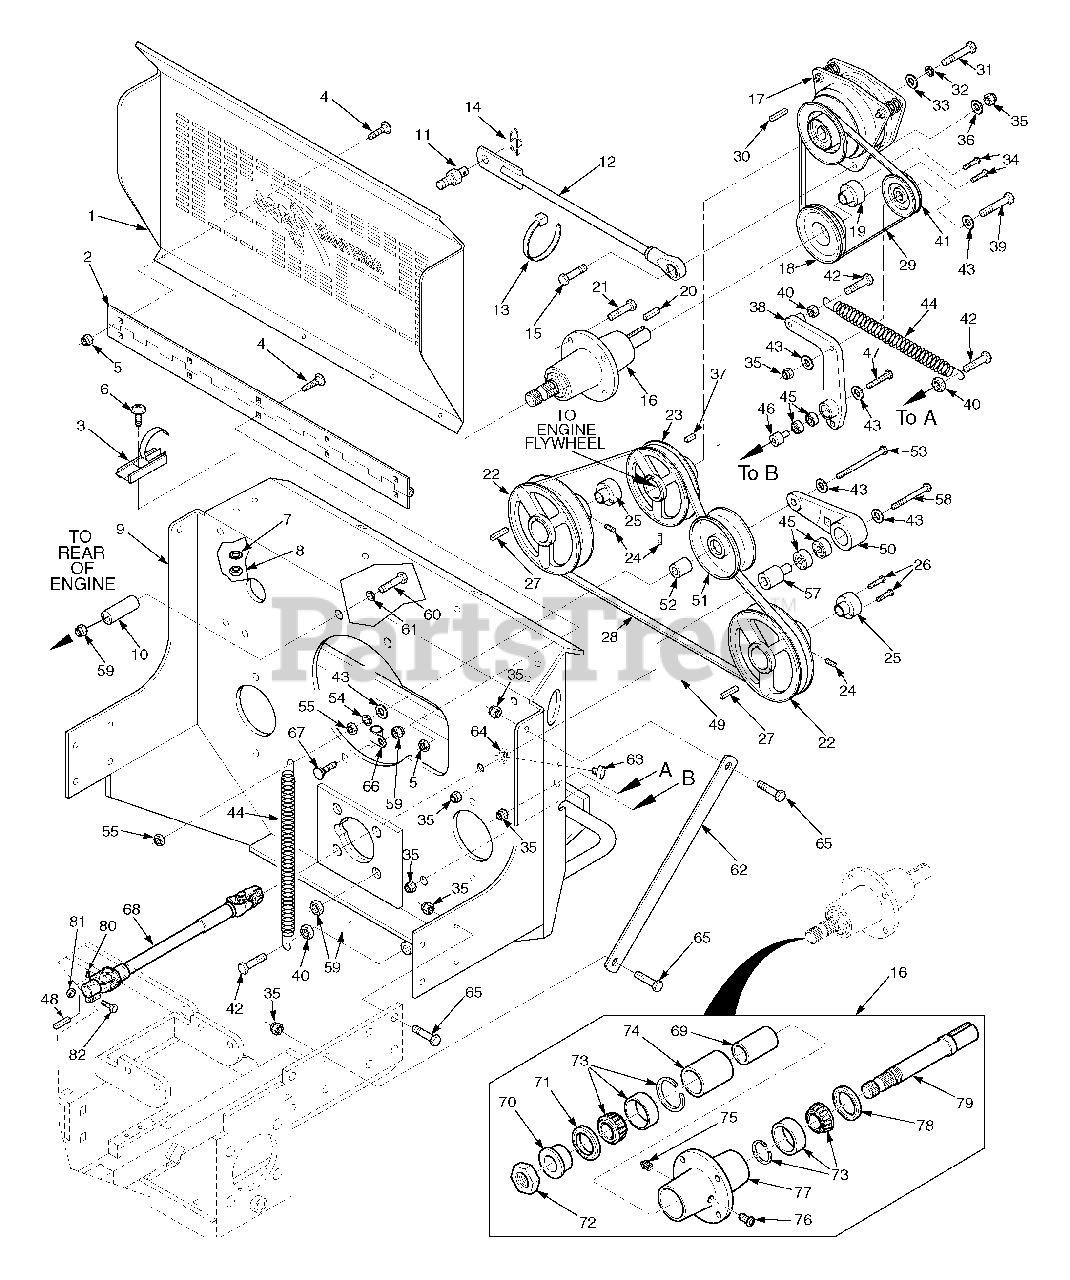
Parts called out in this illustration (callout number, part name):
1	Belt Guard, Rear
2	Hinge, Rear Belt Guard
3	Latch, Hood
4	Carr. Bolt 1/4-20 x .5"
5	Nut, Serr. Flg. 1/4-20
6	Screw, #10-32 x .5, Phillips Head
7	Lock Washer, #10
8	Nut, #10-32
9	Weldment, Pump Mounting
10	Spacer, Engine
11	Stud, Anti-Rotation
12	Linkage Assembly, Anti-Rotation
13	Tie, Cable
14	Pin, Rue
15	Bolt, Hex Head 3/8-16 x 1.50"
16	Spindle Assembly, Deck Drive
17	Clutch, Electric PTO
18	Pulley, 6.35" dia. Tapered Bore
19	Hub, Tapered 1" dia.
20	Key, 1/4 x 1/4 x 1.5"
21	Bolt, Hex Head 5/16-18 x 1-1/2" Grade 8
22	Pulley, 6.25" OD, Tapered
23	Pulley, 5.45" OD
24	Set Screw, 5/16-18 x .375"
25	Hub, Tapered 17mm Bore
26	Bolt, Hex Head 1/4-20 x 1" Grade 8
27	Key, 5mm x 5mm x 30mm
28	Belt, Pump Drive
29	Belt, Deck Drive
30	Key, 1/4 x 1/4 x 2.5"
31	Bolt, Hex Head 7/16-20 x 2.5"
32	Lock Washer 7/16"
33	Flat Washer 7/16 x .469 x 1.75 x .25"
34	Bolt, Hex Head 1/4-20 x 1.375"
35	Nut, Elastic Stop 3/8-16
36	Flat Washer 3/8, .391 x .938 x .105"
37	Key, 1/4 x 1/4 x 1.00"
38	Idler Arm
39	Bolt, Hex Head 3/8-16 x 2.25"
40	Nut, Serr. Flg. 3/8-16
41	Pulley, PTO Idler
42	Bolt, Hex Head 3/8-16 x 1.5" Grade 8
43	Flat Washer 3/8" Grade 8
44	Spring
45	Bearing
46	Pivot, Idler - Short
47	Bolt, Hex Head 3/8-16 x 2-3/4"
48	Key, 1/4 x 1/4 x 1"
49	Bolt, Hex Head 5/16-18 x 1.00"
50	Idler Arm
51	Pulley, Pump Idler
52	Spacer
53	Bolt, Hex Head 3/8-16 x 3.75" Grade 8
54	Lock Washer 3/8" .638 x .380 x .094"
55	Nut 3/8-16
56	Nut, Elastic 3/8-16
57	Pivot, Idler - Long
58	Bolt, Hex Head 3/8-16 x 3-1/4"
59	Nut, Elastic 5/16-18
60	Bolt, Hex Head 5/16-18 x 3.00"
61	Lock Washer 5/16"
62	Brace, Engine Mounting Plate
63	Bumper, Rubber
64	Nut, Serr. Flg. 5/16-18
65	Bolt, Hex Head 3/8-16 x 1.00"
66	Clamp, Wire
67	Bolt, Carr. 5/16-18 x .75"
68	Driveshaft
69	Spacer, Inside
70	Bushing
71	Seal, 2.00 OD x 1.625 Bore
72	Nut, 1.06-18
73	Roller Bearing Assembly
74	Spacer, Outside
75	Grease Fitting 1/4-28 Self Tapping
76	Relief Fitting
77	Spindle Housing
78	Seal, 2.00 OD x 1.5 Bore
79	Shaft, Spindle
80	Screw, Set 3/8-16 x 3/8"
81	Nut, Center Lock 3/8-16
82	Bolt, Hex Head 3/8-16 x 1-3/4"
